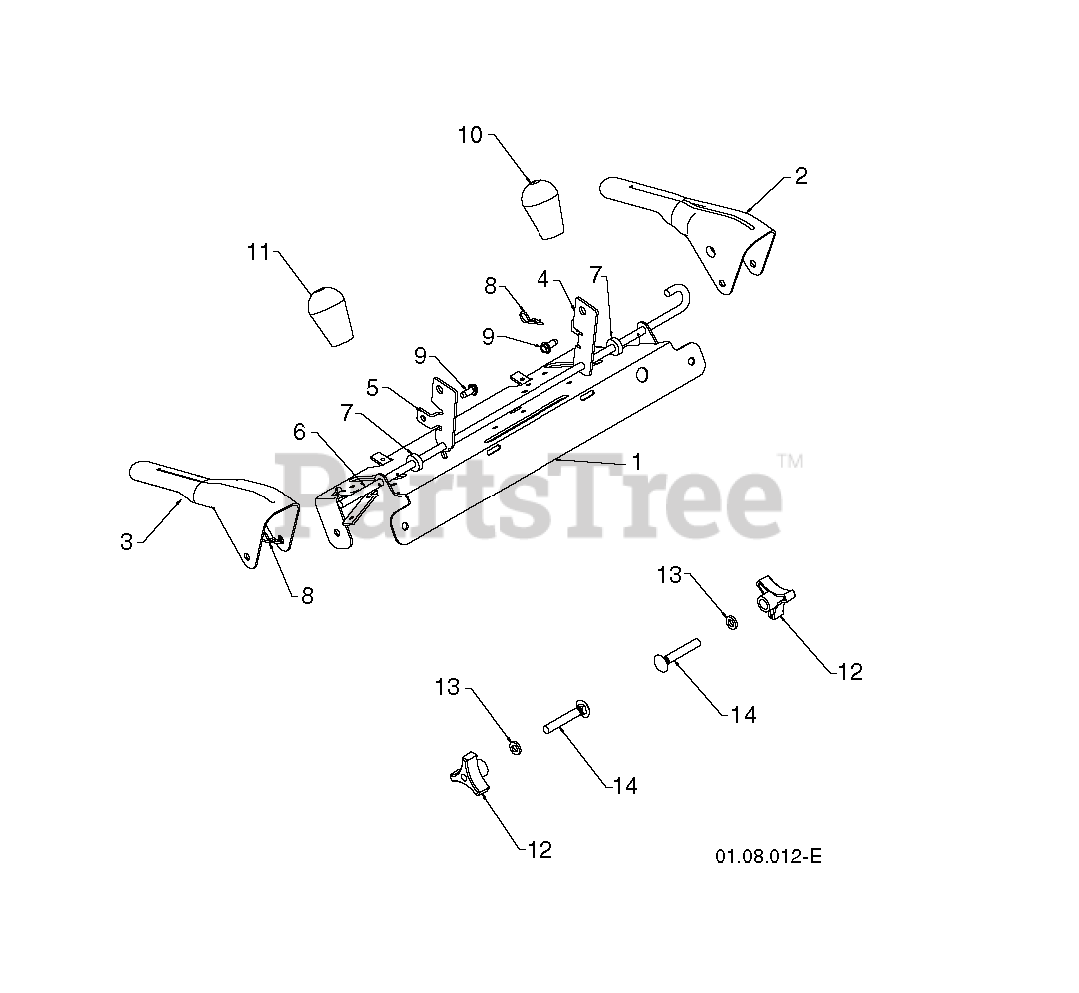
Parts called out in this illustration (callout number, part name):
1	PANEL.CONTROL.PNT.BLACK
2	LEVER.CONTROL.LH.BLACK
3	LEVER.CONTROL.RH.GREY
4	ARM.TRACTION.ROD.YZ
5	ARM.IMPELLER.ROD.SNOW
6	BAIL.CONTROL.INTERLOCK
7	SPACER.CONTROL.LEVER
8	SPRING RETAINER
9	SCREW 14-20 X 5/8
10	KNOB LEVER, BLACK
11	RED KNOB SHIFTER
12	KNOB.HANDLE.3/8.TRI-POINT.BLAC
13	WASHER
14	BOLT 3/8-16 X 2-1/4
